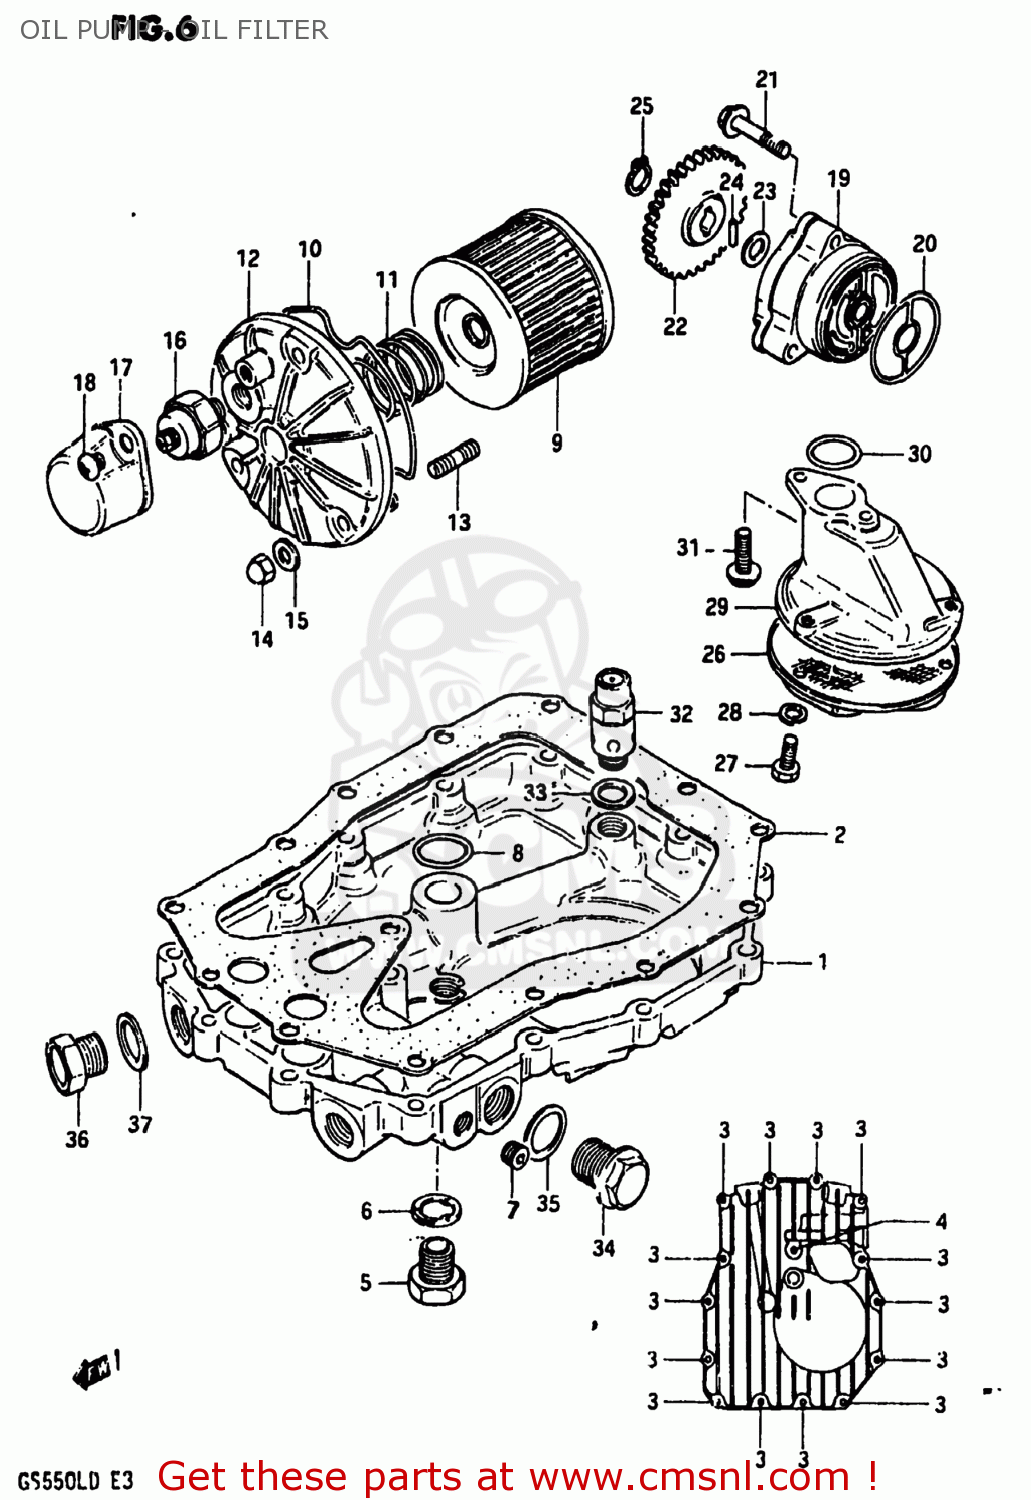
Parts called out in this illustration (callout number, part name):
1	PAN,OIL
2	GASKET,OIL PAN (MCA)
3	BOLT
4	BOLT 6X35
5	PLUG
6	GASKET(14X19.2X2) (NAS)
7	PLUG
8	O RING(D:3.2,ID:17.8)
9	FILTER ASSY,ENGINE OIL
10	O RING,OIL FILTER CHAMBER CAP
11	SPRING
12	CAP,ENGINE OIL FILTER
13	STUD 6X20
14	NUT 6MM
15	WASHER
16	SWITCH ASSEMBLY
17	COVER,OIL PRESSURE SWITCH
18	SCREW
19	PUMP ASSEMBLY,ENGINE OIL
20	O-RING,OIL PUMP
21	BOLT(6X32)
22	GEAR,OIL PUMP DRIVEN
23	SHIM
24	PIN(4X15.8)
25	CIRCLIP
26	STRAINER,ENGINE OIL
27	BOLT
28	LOCK WASHER
29	PROTECTOR,OIL STRAINER
30	O RING(D:3.2,ID:17.8)
31	BOLT,REAR
32	REGULATOR ASSEMBLY,ENGINE
33	WASHER
34	PLUG
35	O RING(D:2.4,ID:16.8)
36	PLUG
37	GASKET(14X20X1.5) (NAS)
